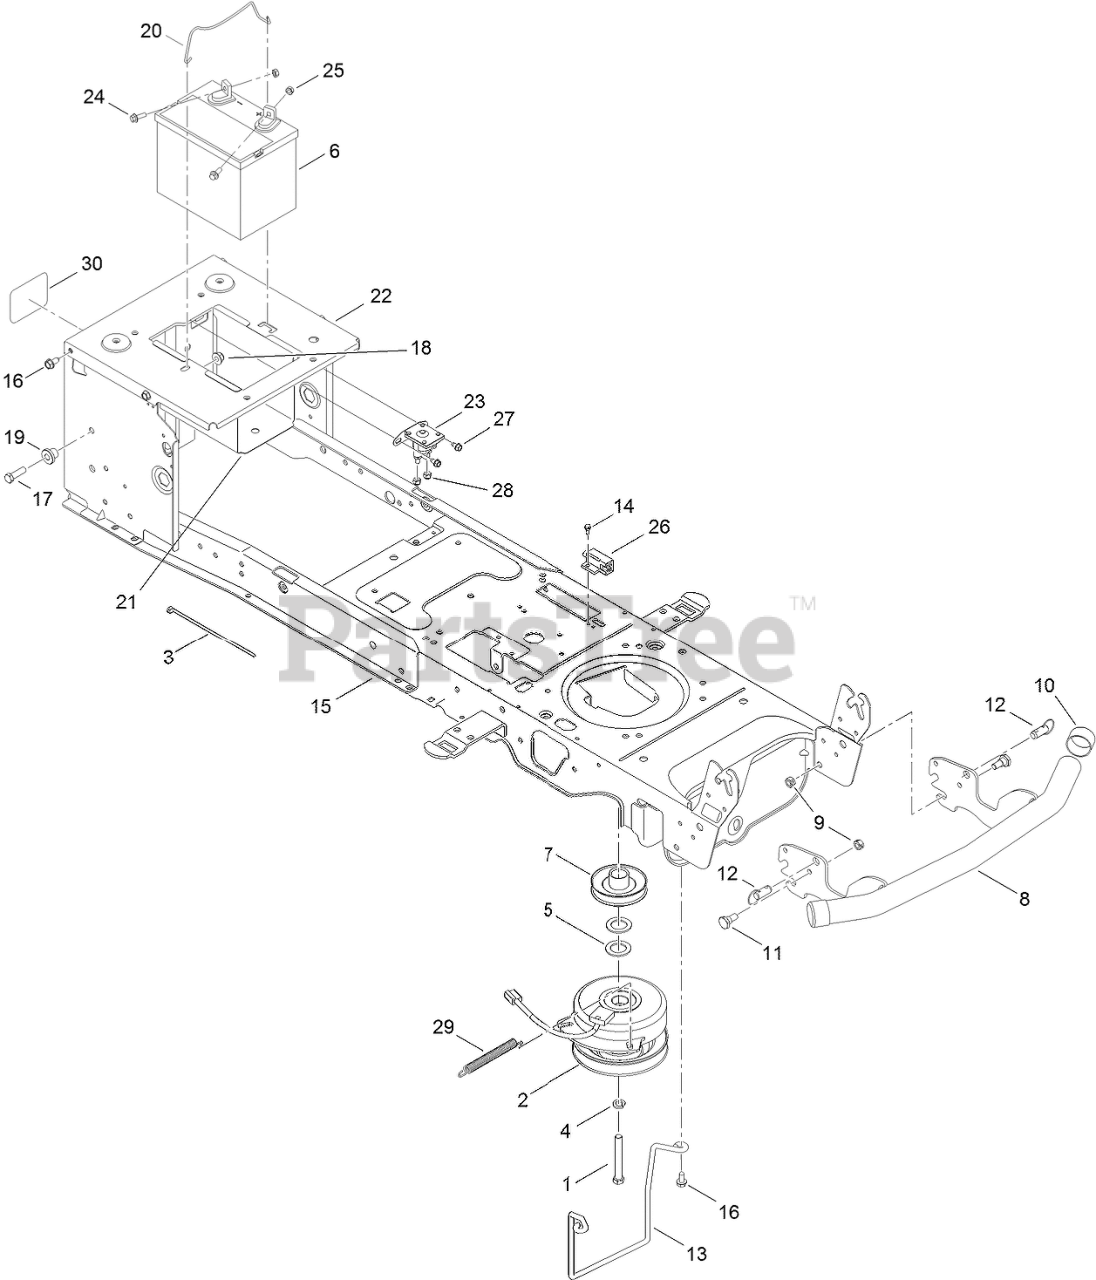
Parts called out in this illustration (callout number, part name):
1	SCREW-HH
2	CLUTCH-PTO, ELECTRIC
3	TIE-CABLE
4	WASHER-LOCK
5	WASHER-FLAT
6	BATTERY-245, CCA (DRY FLAT TOP)
7	PULLEY-ENGINE
8	BUMPER-UNIVERSAL
9	NUT-LOCK
10	CAP-HUB
11	BOLT-SHOULDER
12	PIN-RELEASE, QUICK
13	ROD-KEEPER
14	BOLT-SHOULDER
15	LOWER FRAME ASM
16	SCREW-TAP
17	SCREW-HH
18	NUT-LOCK, FLANGE
19	SPACER-SHOULDER
20	ROD-HOLDDOWN, BATTERY
21	TRAY-BATTERY
22	BRACKET-FRAME, SEAT
23	SOLENOID-12V, 2 POST 2 Tab
25	NUT-SEMS
26	SWITCH-INTERLOCK, NO/NC
27	SCREW-TAP
28	NUT-LOCK, FLANGE
29	SPRING-EXTENSION
30	DECAL-RELEASE
